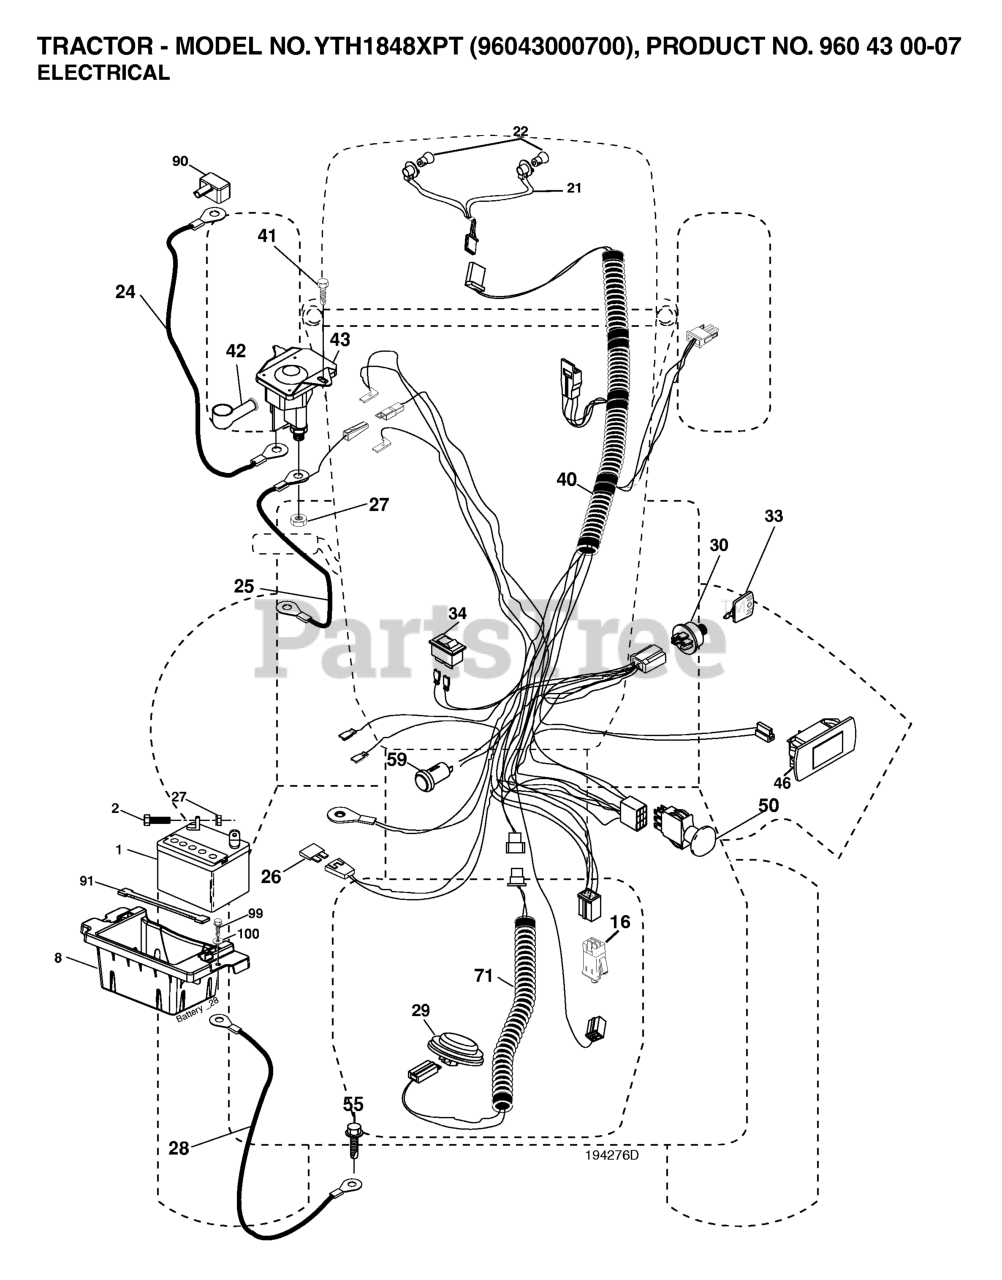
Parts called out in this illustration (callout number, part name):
1	BATTERY 12V .35 AMP
2	BOLT.HEX.1/4.X.3/4.DICHROMATE
8	BOX.BATTERY.MOUNT.FRONT.LT
16	SWITCH INTERLOOK PUSH-IN
21	HARNESS ASSY LIGHT
24	CABLE.BATT.POS.WIRE.TG.DA SOL
26	FUSE 20AMP
27	NUT
28	CABLE GROUND 6 GA 21" 90T BLK
29	SWITCH.SEAT.DELTA.OPC.
30	SWITCH.IGN.DELTA.W.LGH.ROS
33	KEY MLD GEN DELTA
40	HARNESS-CHASSIS SUB
41	BOLT
42	TERMINAL COVER
43	SOLENOID.W/BRASS.PLUNGER
46	GAUGE.SERVICEMINDER.HR
50	RP.PTO.SWITCH.8 TERMINAL.BLACK
55	Screw 5/16-18 x 1/2 Hex, Self Tapping 5/16-18 x 1/2
90	COVER TERMINAL
91	STRAP.BATTERY.MOUNT.FRONT(2 2)
99	SCREW HEXWSHR 1/4-20X3/4
